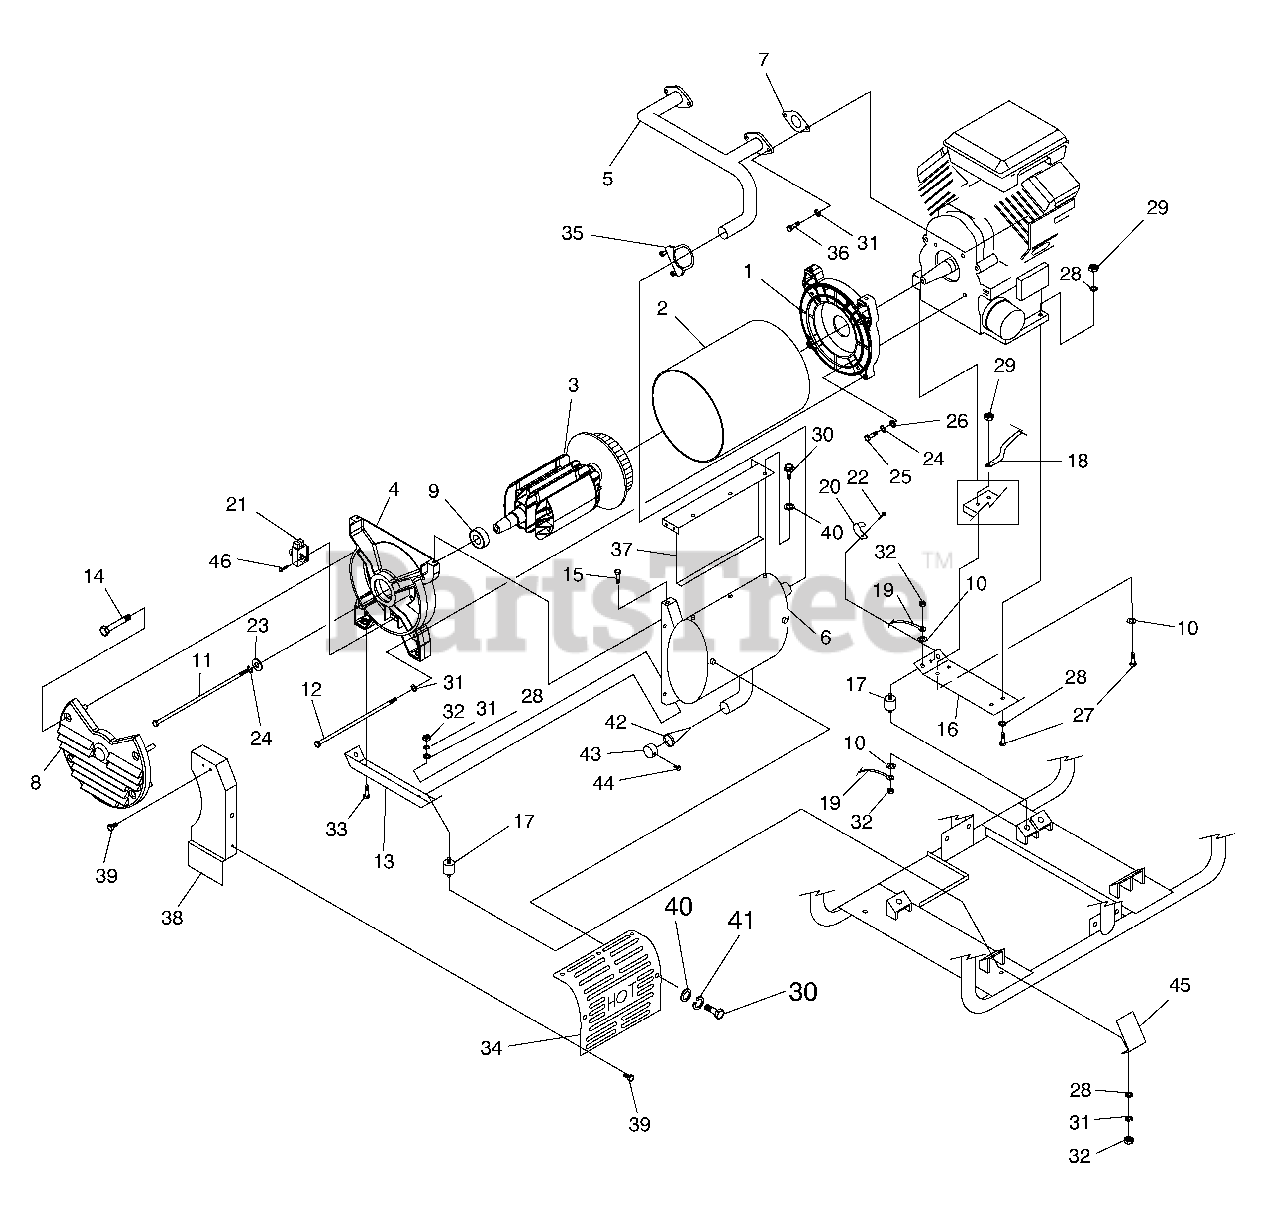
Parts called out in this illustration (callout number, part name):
1	ADAPTOR, ENGINE
2	STATOR 15KW
3	ASSEMBLY, ROTOR WITH FAN 15KW
4	CARRIER, REAR BEARING
5	EXHAUST MANIFOLD
6	MUFFLER
7	GASKET, EXHAUST
8	COVER, ALTERNATOR AIR IN
9	BEARING
10	5/16 SPECIAL LOCK WASHER
11	SCREW IHHC 3/8-24 X 15.50 G5
12	SCREW IHHC M8-1.25 X 400 G8.8
13	BRACKET, ALT MOUNTING
14	SCREW HHTT #10-32 X 1.75
15	SCREW HHTT M8-1.2 X 20
16	ENGINE MOUNTING PLATE
17	RUBBER MOUNT
18	BATTERY CABLE, BLACK
19	EARTH STRAP 3/8X 3/8
20	CLIP-J VINYL COAT .625 ID
21	ASSEMBLY, BRUSH HOLDER
22	SCREW TAP-R #10-32 X 9/16
23	WASHER FLAT 3/8 ZINC
24	WASHER LOCK 3/8
25	SCREW HHC 3/8-16 X 1-1/4 G5
26	WASHER FLAT 3/8-M10 ZINC
27	SCREW HHC M8-1.25 X 50 G8.8
28	WASHER FLAT 5/16 ZINC
29	NUT LOCK HEX M8-1.25 NYLON INSERT
30	SCREW HHC M6-1.0 X 12
31	WASHER LOCK M8-5/16
32	NUT HEX 5/16-18 STEEL
33	SCREW TAPTITE 3/8-16 X 3/4 BP
34	SHIELD, MUFFLER HEAT
35	U-BOLT & SADDLE
36	SCREW SHC M8-1.25 X 18
37	PANEL, MUFFLER BOX BACK
38	PANEL, MUFFLER BOX END
39	SCREW HHTT M6-1.0 X 12
40	WASHER FLAT M6-1/4
41	WASHER LOCK M6-1/4
42	SPARK ARRESTOR SCREEN
43	RETAINER, SPARK ARREST SCREEN
44	SCREW HHTT M4-0.7 X 8
45	SHIELD, RUBBER MOUNT
46	SCREW HHTT M5-0.8 X 16
